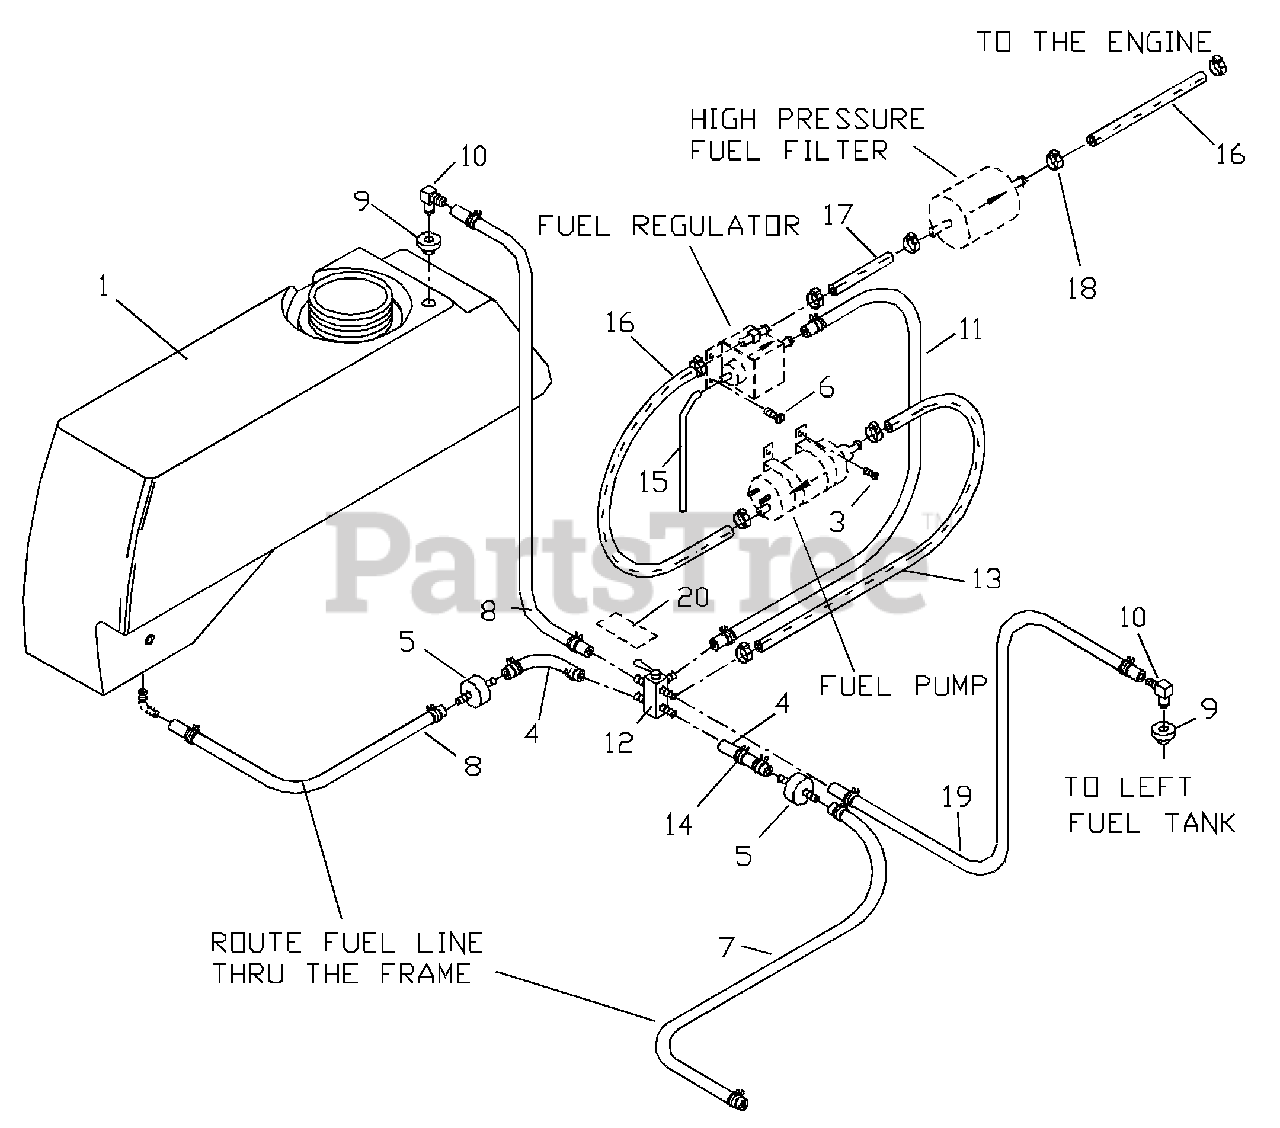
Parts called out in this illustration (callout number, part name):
1	FUEL TANK RT.
2	FUEL TANK LT.
3	SCREW SELF TAP
6	HCS 1/4 SELF TAP
7	FUEL LINE
8	FUEL LINE
9	RUBBER GROMMET
11	FUEL LINE
12	FUEL VALVE
13	EFI HOSE
14	HOSE CLAMP
16	EFI HOSE
17	EFI HOSE
